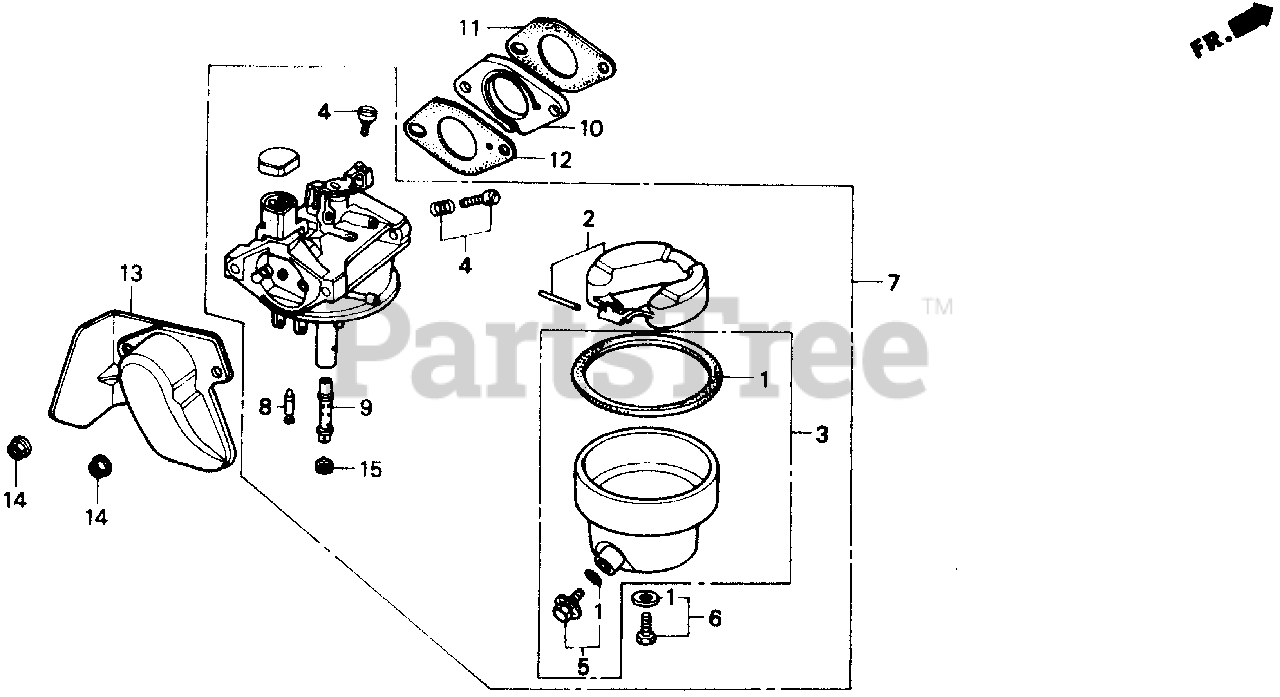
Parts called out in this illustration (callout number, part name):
1	GASKET SET
3	CHAMBER SET, FLOAT
4	SCREW SET A
5	SCREW SET, DRAIN (NOT AVAILABLE)
6	SCREW SET B
7	CARBURETOR ASSY.
8	VALVE, FLOAT
9	NOZZLE, MAIN
10	INSULATOR, CARBURETOR
11	GASKET, INSULATOR
12	GASKET, CARBURETOR
13	GUIDE, AIR (NOT AVAILABLE)
14	NUT, FLANGE (6MM)
15	JET, MAIN (#55)
15	JET, MAIN (#58)
15	JET, MAIN (#60)
